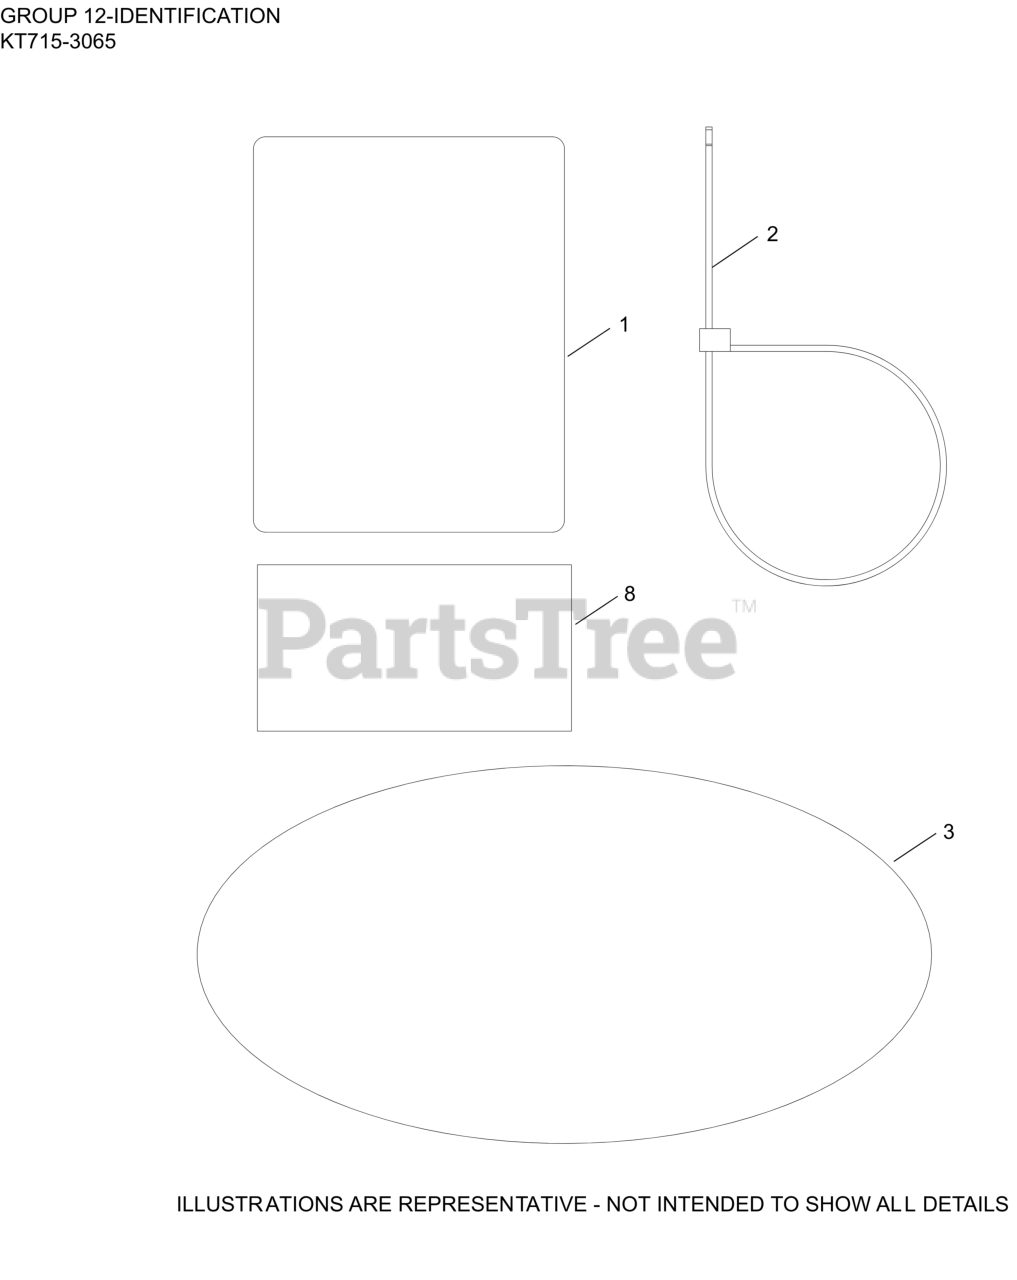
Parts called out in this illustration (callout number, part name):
1	LABEL, CLEAR LAMINATION
3	LABEL, 7000 SERIES KT715 (20 HP)
8	DECAL, USA
